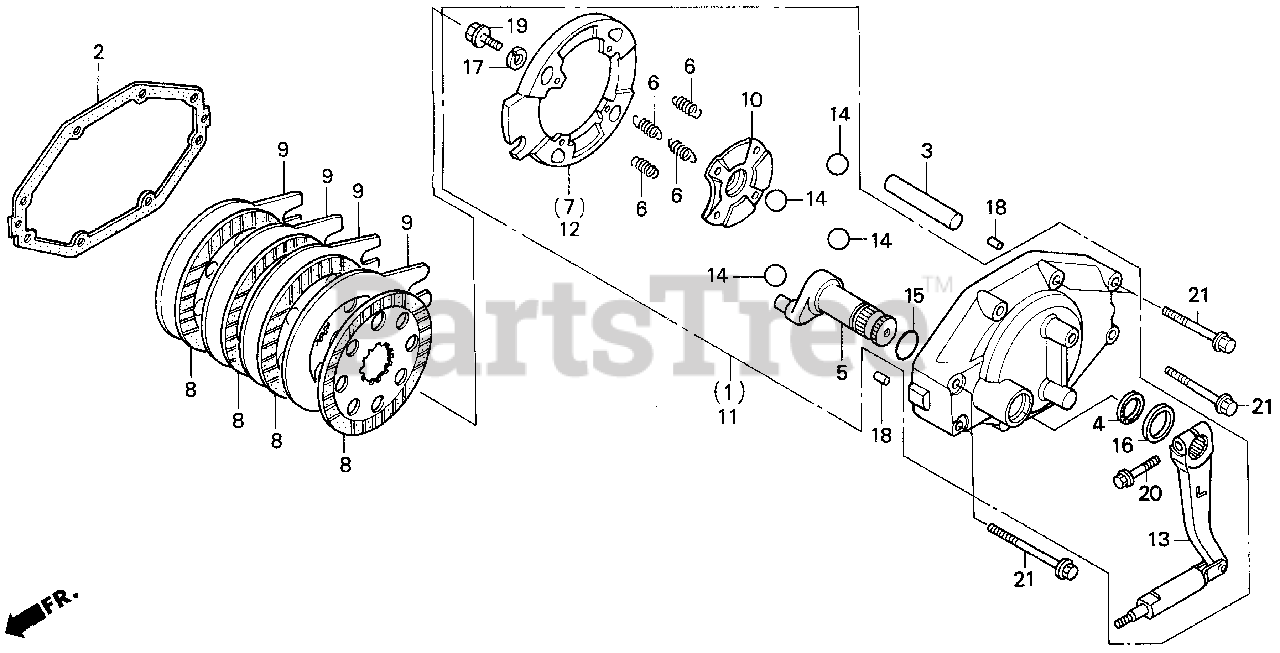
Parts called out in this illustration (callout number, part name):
1	ACTUATOR ASSY., R. BRAKE
2	GASKET, BRAKE COVER
3	PIN, BRAKE ANCHOR
4	DUST SEAL, BRAKE
5	ARM, BRAKE CRANK
6	SPRING, RETURN
7	ACTUATOR, R. BRAKE
8	PLATE, BRAKE FRICTION
9	PLATE, BRAKE STATOR
10	PLATE, SPRING HOOK
11	ACTUATOR ASSY., L. BRAKE
12	ACTUATOR, L. BRAKE
13	ARM, BRAKE
14	BALL, STEEL (3/4)
15	O-RING (21.8X2.4)
16	WASHER, PLAIN (26MM)
17	WASHER, SPRING (8MM)
18	PIN, DOWEL (8X14)
19	BOLT, FLANGE (8X16)
20	BOLT, FLANGE (8X35)
21	BOLT, FLANGE (8X45)
